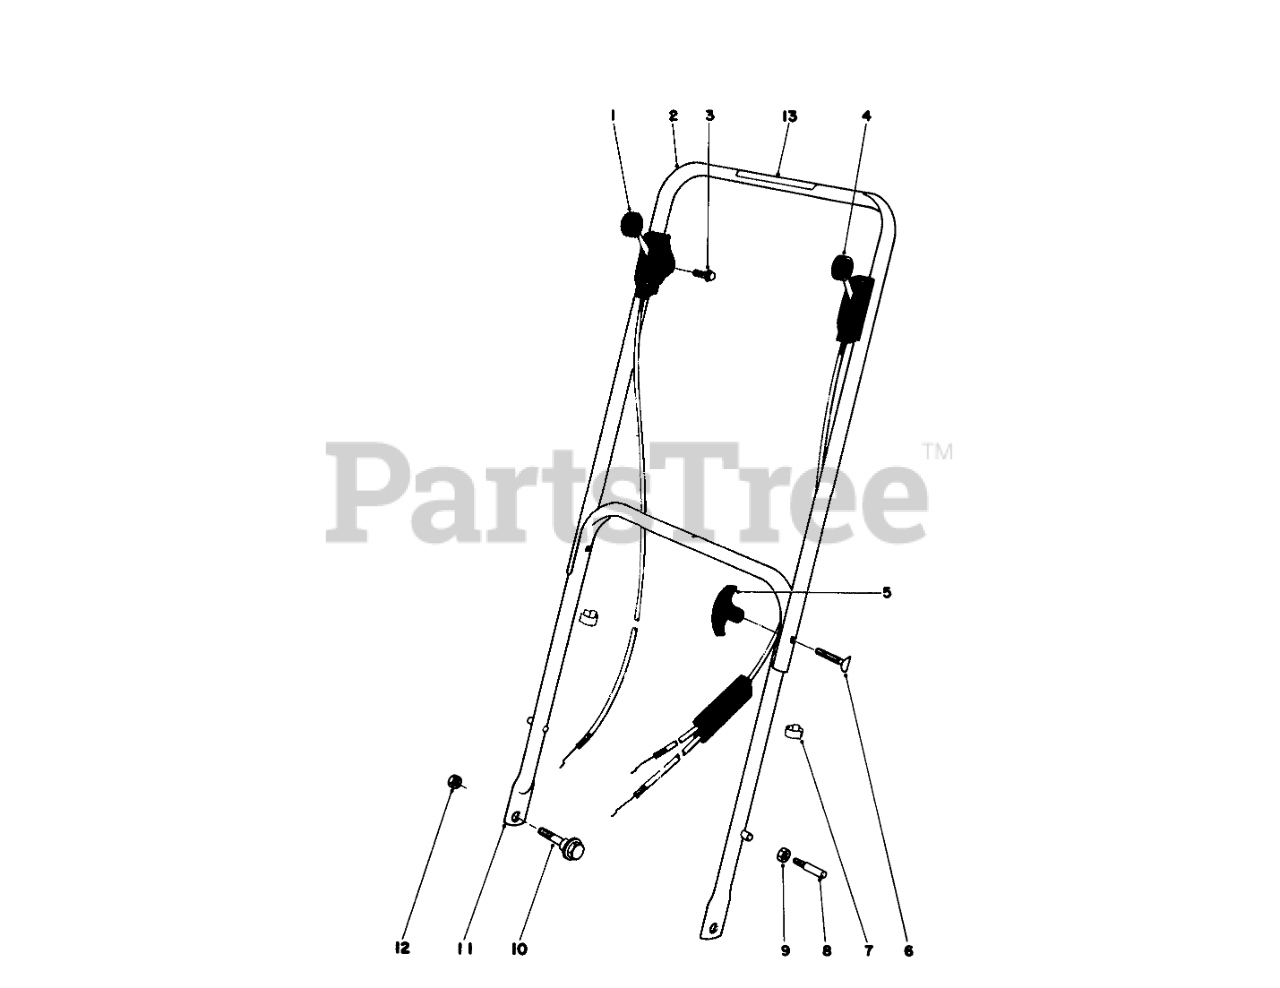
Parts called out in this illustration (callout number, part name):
1	Throttle Control
2	UPPER HANDLE
4	Traction Control
6	HANDLE SCREW
7	BOWDEN CLIP
8	HANDLE PIN
9	Nut
10	SCREW-SHOULDER
11	Lower Handle
12	Nut
13	Decal
